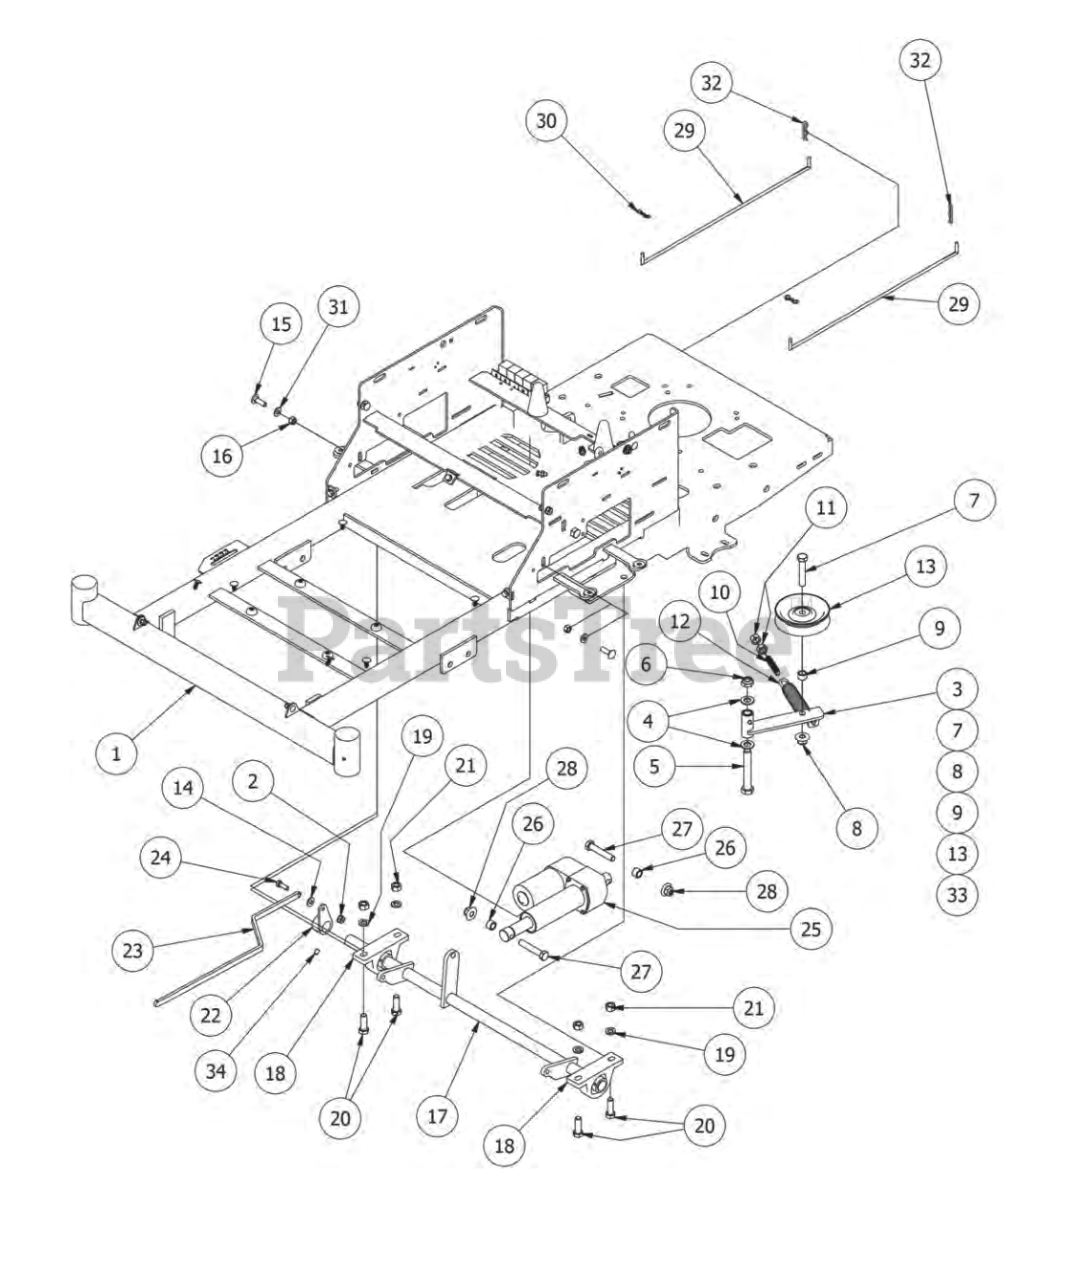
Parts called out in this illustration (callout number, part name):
1	ZT/CZT Frame 2013 Models
2	5/16-18 Nylon Flange Nut
3	Pump Idler Bracket
4	635 ID Plastic Washer
5	5/8" x 4" Hex Bolt
6	5/8" Nylock (1/2 Jam)
7	1/2" x 2 3/4" Hex Bolt
8	1/2-13 Nylon Flange Nut-Orange
9	1/2 x 1/2 Spacer
10	All Thread-pump Idler Tensioner
11	1/2" Hex Nut
12	2009 Deck/Pump Idler Spring
13	43/4" Idler Pulley
14	.360 ID Plastic Washer
15	3/8" x 1 1/4" Carriage Bolt
16	3/8" Hex Nut
17	Actuator Bar-Transaxle
18	pillow block 2bolt sealmaster
19	1/2" Lock Washer
20	1/2" x 1 1/2" Hex Bolt
21	1/2" Hex Nut
22	Height Indicator Lever
23	Height Indicator Bar
24	5/16" x 1" Bolt
26	1/2 x 1/2 Spacer
27	1/2" x 2 3/4" Hex Bolt
28	1/2-13 Nylon Flange Nut-Orange
29	ZT Neutral level rod 2011
31	3/8" Flat Washer
32	Neutral Rod Clip
33	Pump Idler Assembly (Components 3,7,8,9,13)
34	5/16 Set Screw
